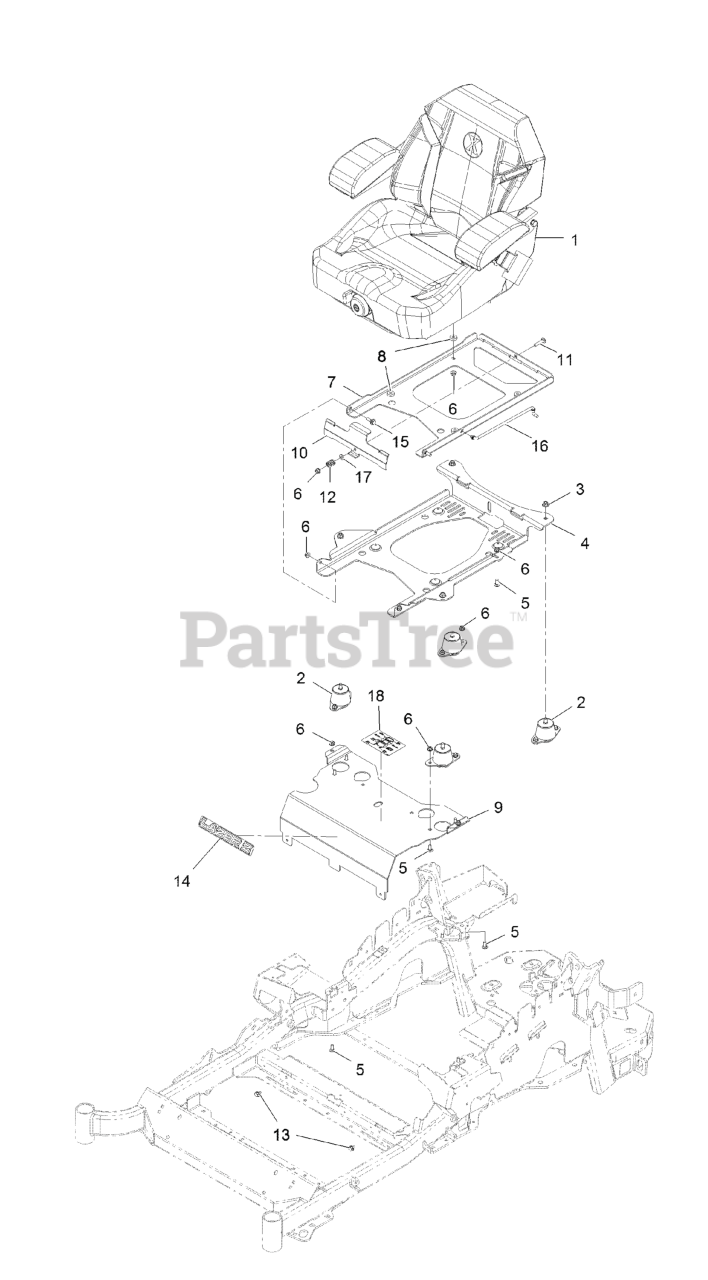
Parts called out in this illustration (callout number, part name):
1	KIT-SUSPENSION SEAT
2	ISOLATOR-SEAT
3	NUT-HF, NI
4	PLATE-TILT, SEAT SUPPORT
5	SCREW-CARR
6	NUT-HF, NI
7	PLATE-FRAME, SEAT
9	Panel-Front, Seat Mount
10	PLATE-LATCH, SEAT
11	BOLT-CARR
12	SPRING-COMPRESSION
14	DECAL, LAZER MODEL
15	SCREW-SHOULDER
16	ROD-PROP
17	WASHER-PLAIN
18	DECAL-SERVICE AID
